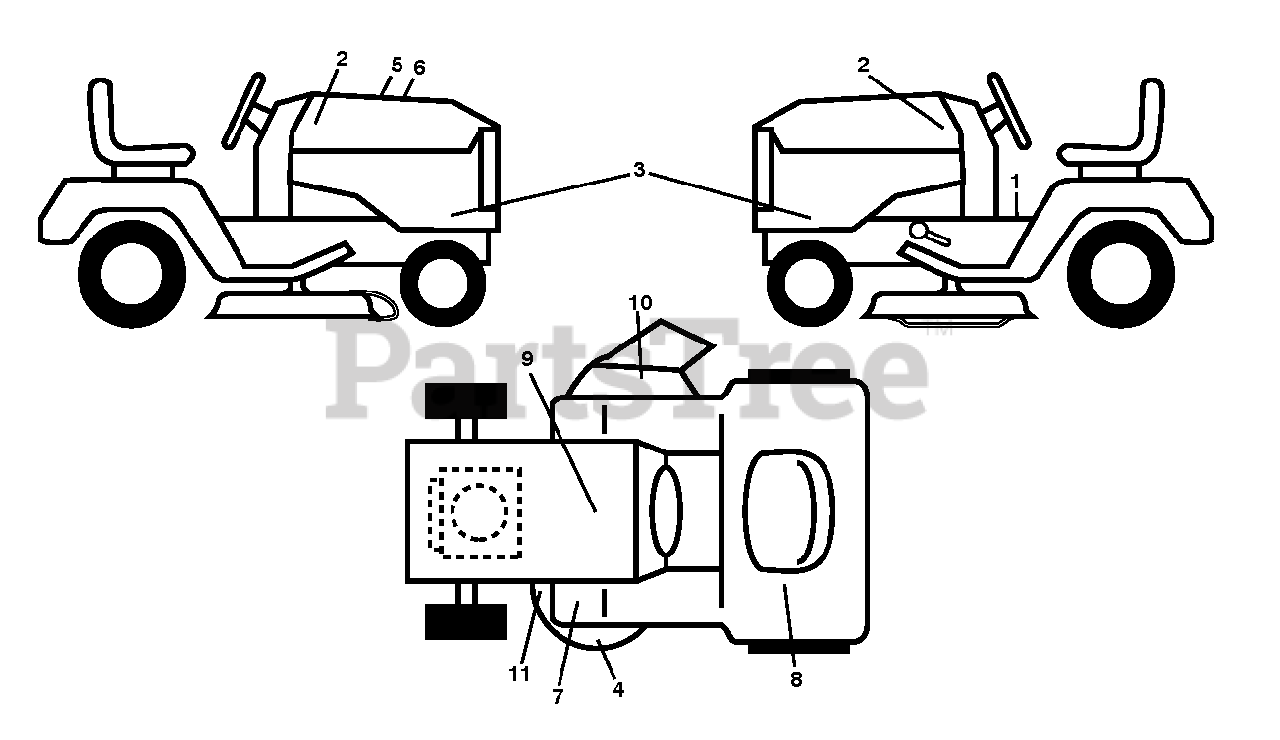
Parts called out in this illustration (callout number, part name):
1	DECAL.FENDER.WARNING
2	RP.DECAL.BADGE.170MM.TEXTLOGO
3	DECAL.SDPNL.HUSQGT2.MS668.YTH2
4	DECAL, NO STEP
5	DECAL.WARNING.CUST.RESP.E85.
7	DECAL.PEDAL.HUSQ.CROWN
8	DECAL.WARN.RESERVE.FUEL
9	DECAL BTRY SYMBOLS
10	DECAL, CAUTION
11	DECAL.MOWER.SCH.48/54
